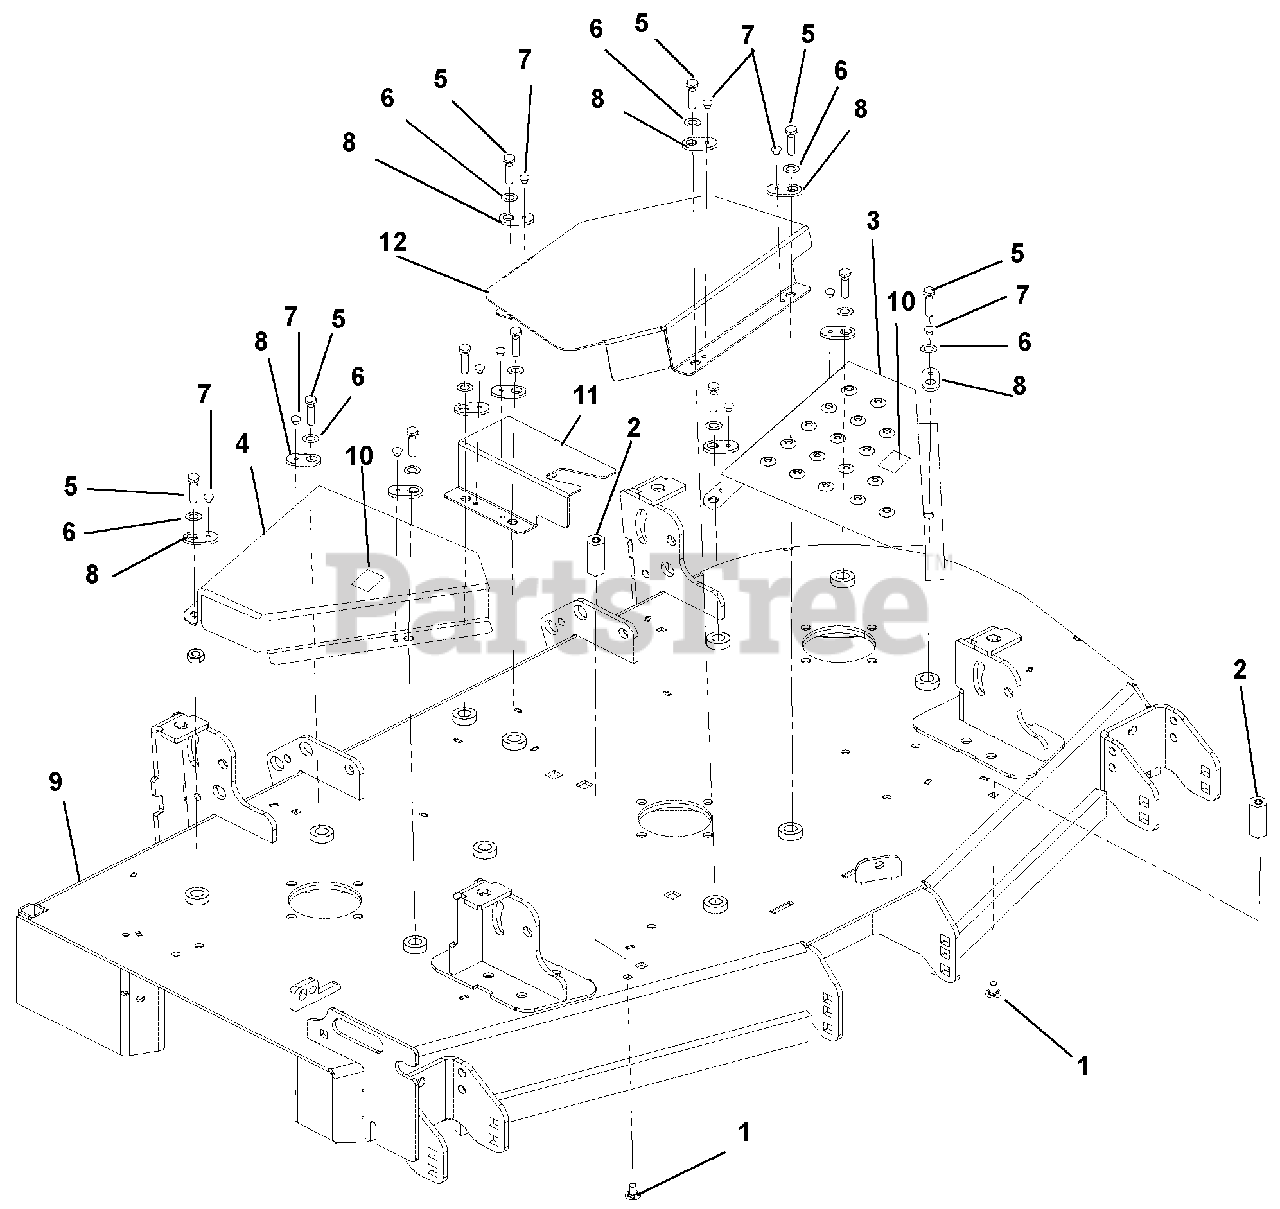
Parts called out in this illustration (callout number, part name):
1	Bolt, Round Head Square Neck .31 - 18 x .75
2	Nut, Coupling .31 - 18 x 3.00
3	Cover, Left Hand Belt, CE
4	Cover, Right Hand CE Belt
5	Bolt, Hex .38-16 x 1.25
6	Washer, Locking, EXT.391 x .682 x .036
7	Rivet, Pop .187
8	Keeper, Bolt
9	Weldment, 48" PT100 Side Dis Deck, CE
10	Decal, Pinch Point
11	Shield, Belt, Rear
12	Shield, Belt, Front
